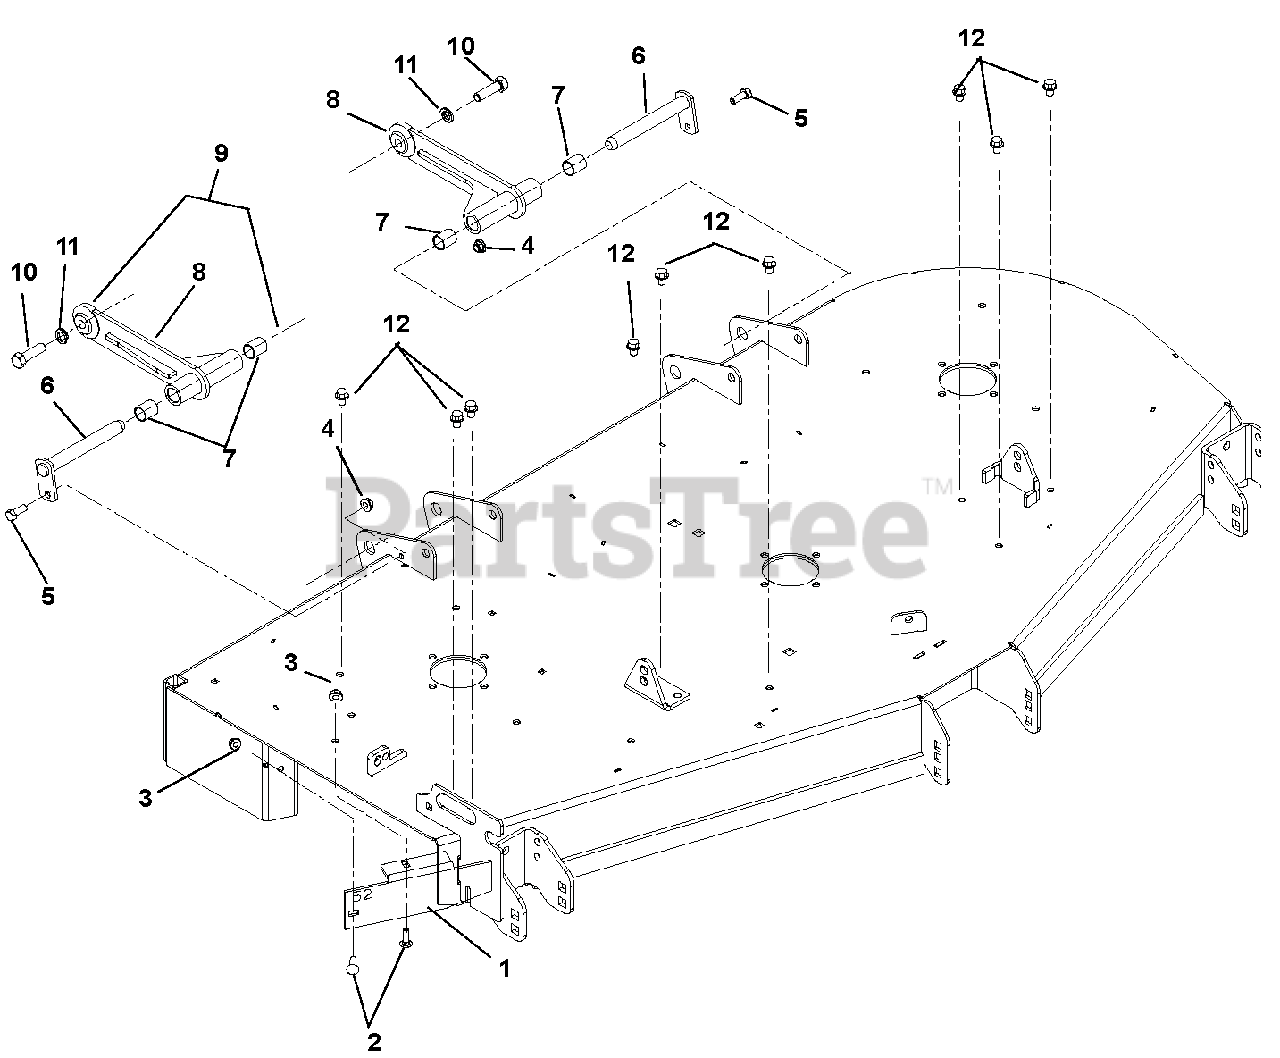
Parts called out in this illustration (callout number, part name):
1	BAFFLE, DISCHARGE 44/48
2	@BLT-RDHDSQNK .31-18X1.00 G5YZ
3	@NUT-LK-NYL-FLG .31-18 YWZC
4	@NUT-LK-NYL-FLG .38-16 YWZC
5	@BLT-HEX .38-16X1.00 GR5 YWZC
6	WELDMENT, MOWER MTG. PIN
7	BRG, .750 X .875 X 1.000
8	DECK PUSHER ARM WMT - BLACK
9	DECK PUSHER ARM ASSEMBLY
10	BLT-HEX .50-13X1.75 GR5EP80 YZ
11	@WSHR-LK .50X.125 REG YWZC
12	@SCR-TAP .38-16X.50 HWH TR YWZ
